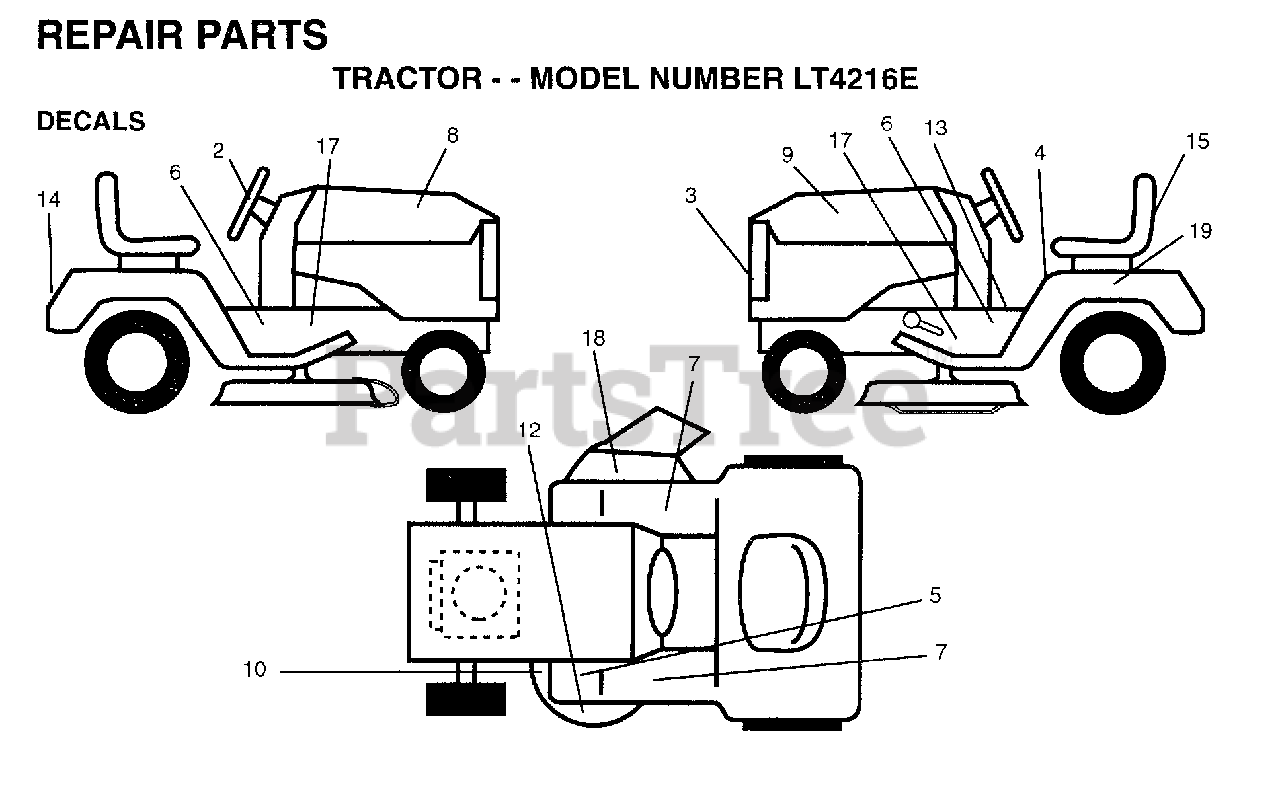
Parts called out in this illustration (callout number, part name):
2	DECAL INST WHL
3	DECAL LOGO GRILLE
4	DECAL CAUT FEND
5	DECAL CLUT/BRAKE
6	DECAL CHASSIS KGR
7	FOOTREST PAD
8	DECAL HOOD RH
9	DECAL HOOD RH
10	DECAL
12	DECAL.DECK.KGRO.
13	DECAL.SADDLE.INST
14	DECAL.FEND.KGRO
17	DECAL.CHAS.KGRO
18	DECAL DANGER CT/F
19	DECAL.BTRY.DANGER
